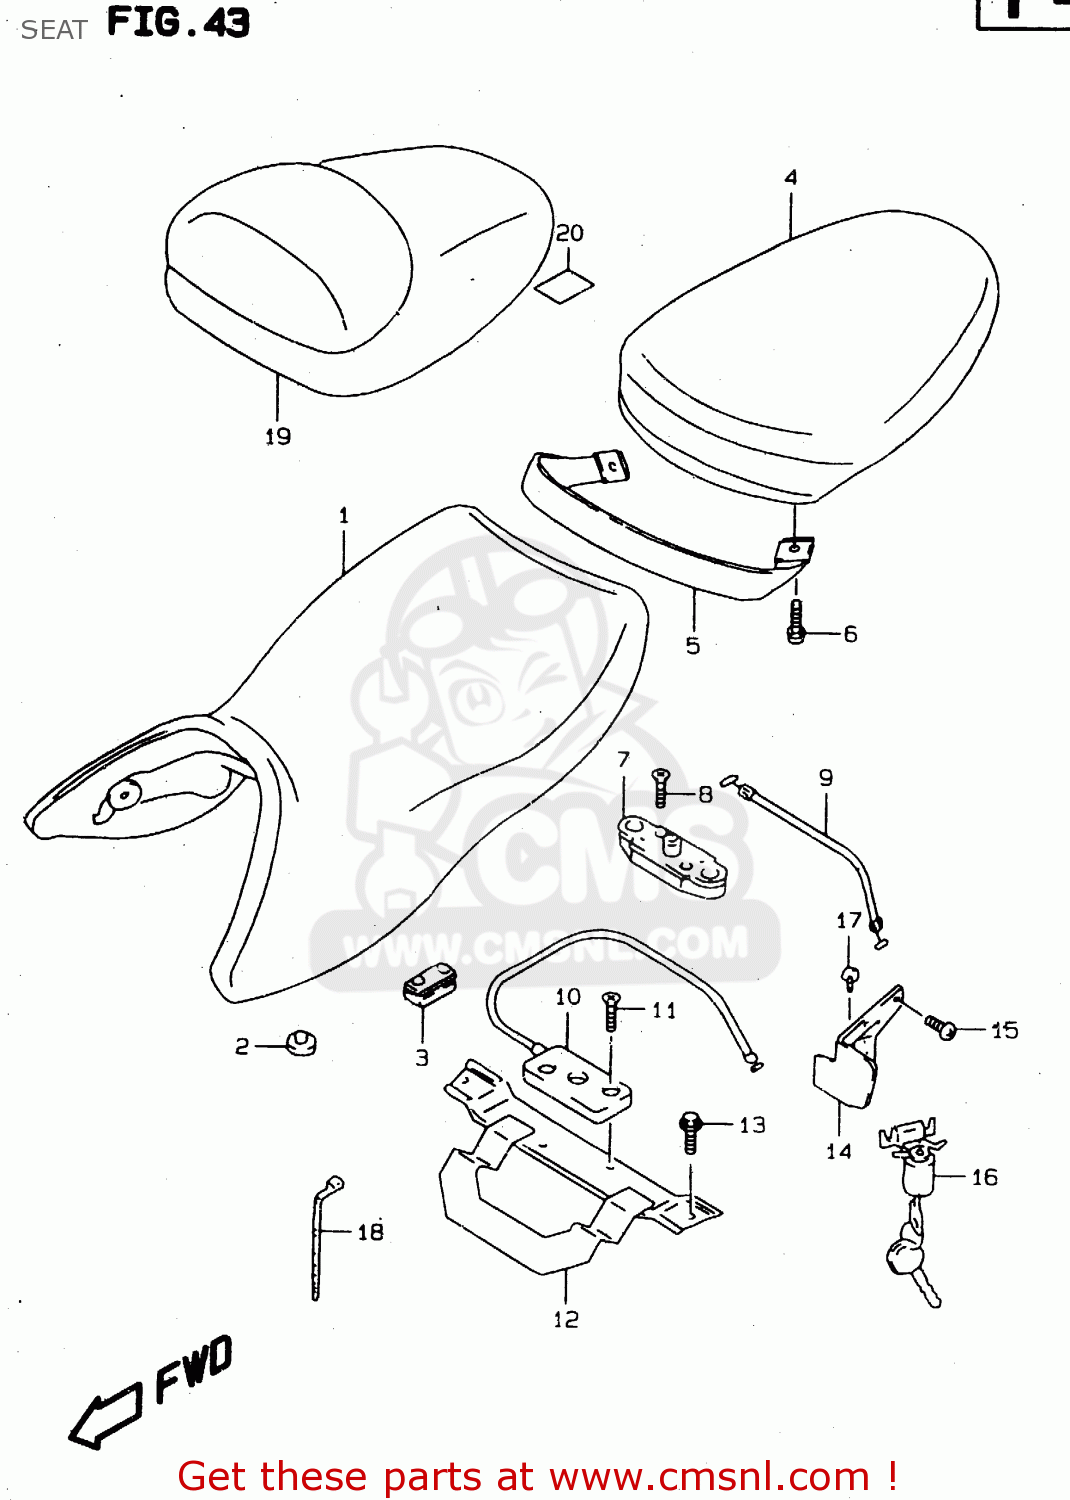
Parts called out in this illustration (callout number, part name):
1	SEAT ASSY(BLACK)
2	CUSHION,SEAT
3	CUSHION,SEAT(40X20X15)
4	SEAT ASSY,PILLION(BLACK)
5	BAND ASSY,PILLION SEAT(BLACK)
6	BOLT
7	BRACKET,SEAT SUPPORT,RIGHT
8	SCREW
9	CABLE,SEAT LOCK
10	BRACKET,SEAT SUPPORT FR
11	SCREW
12	BRACKET,SEAT LOCK
13	BOLT
14	BRACKET,SEAT LOCK KEY CYLINDER
15	SCREW 6X12
16	LOCK SET,SEAT
17	SCREW
18	CLAMP(L:125)
19	BOX,SEAT TAIL(RED)
20	PROTECTOR SET,SEAT TAIL BOX
